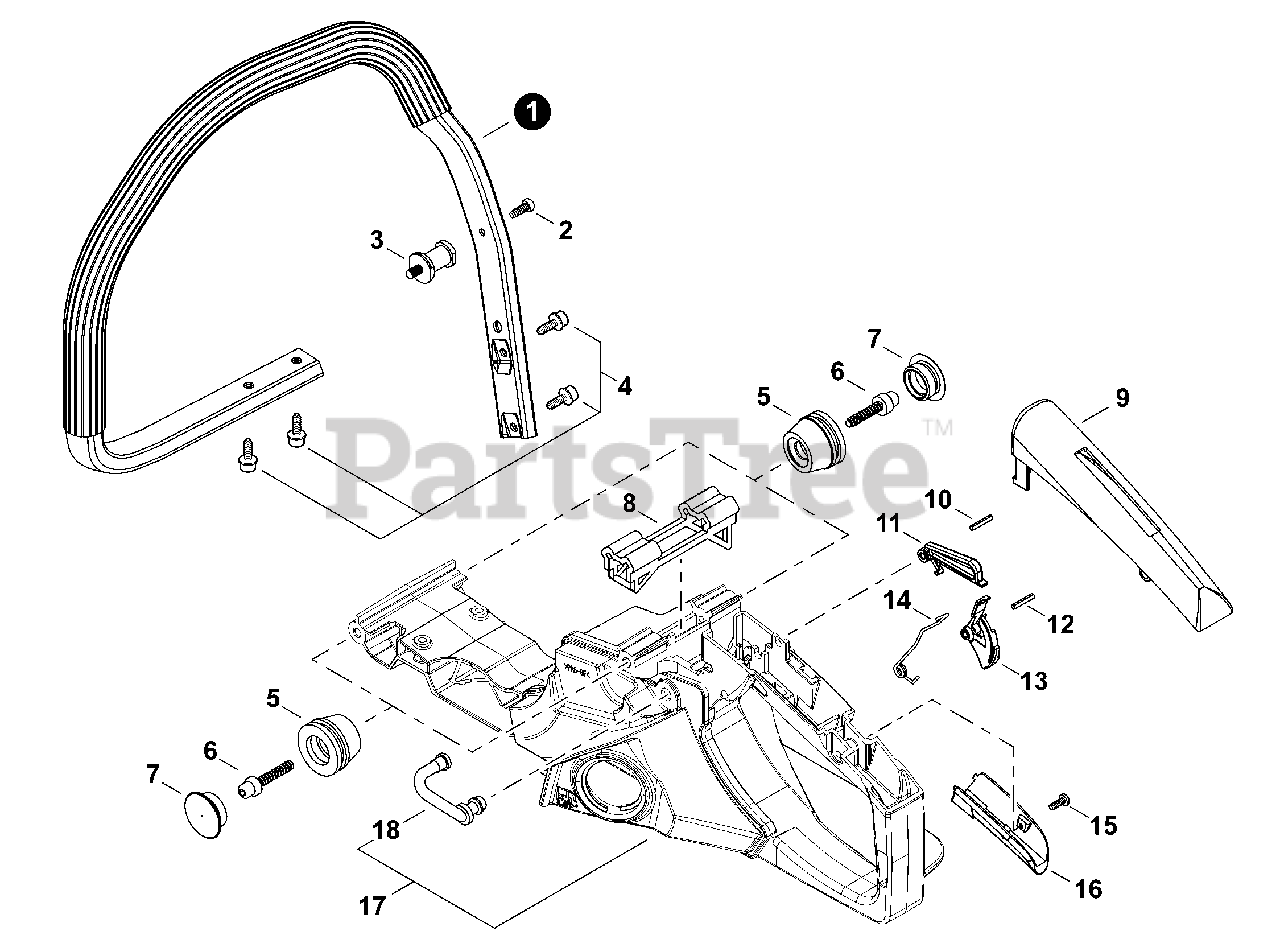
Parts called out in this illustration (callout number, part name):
1	HANDLE, FRONT
2	BOLT M4×14
3	CUSHION 5
4	BOLT, TAPPING M5×16
5	CUSHION 5
7	CAP, CUSHION
8	CUSHION, STOPPER
9	COVER, HANDLE
10	PIN, SPRING Ø4×22 MM
11	LOCKOUT, THROTTLE
12	PIN, SPRING Ø4×25 MM
13	TRIGGER, THROTTLE
14	SPRING, THROTTLE RETURN
15	SCREW, TAPPING M4×22
16	GRIP, LOWER
17	HANDLE ASSY, REAR
18	PIPE, FUEL VENT
